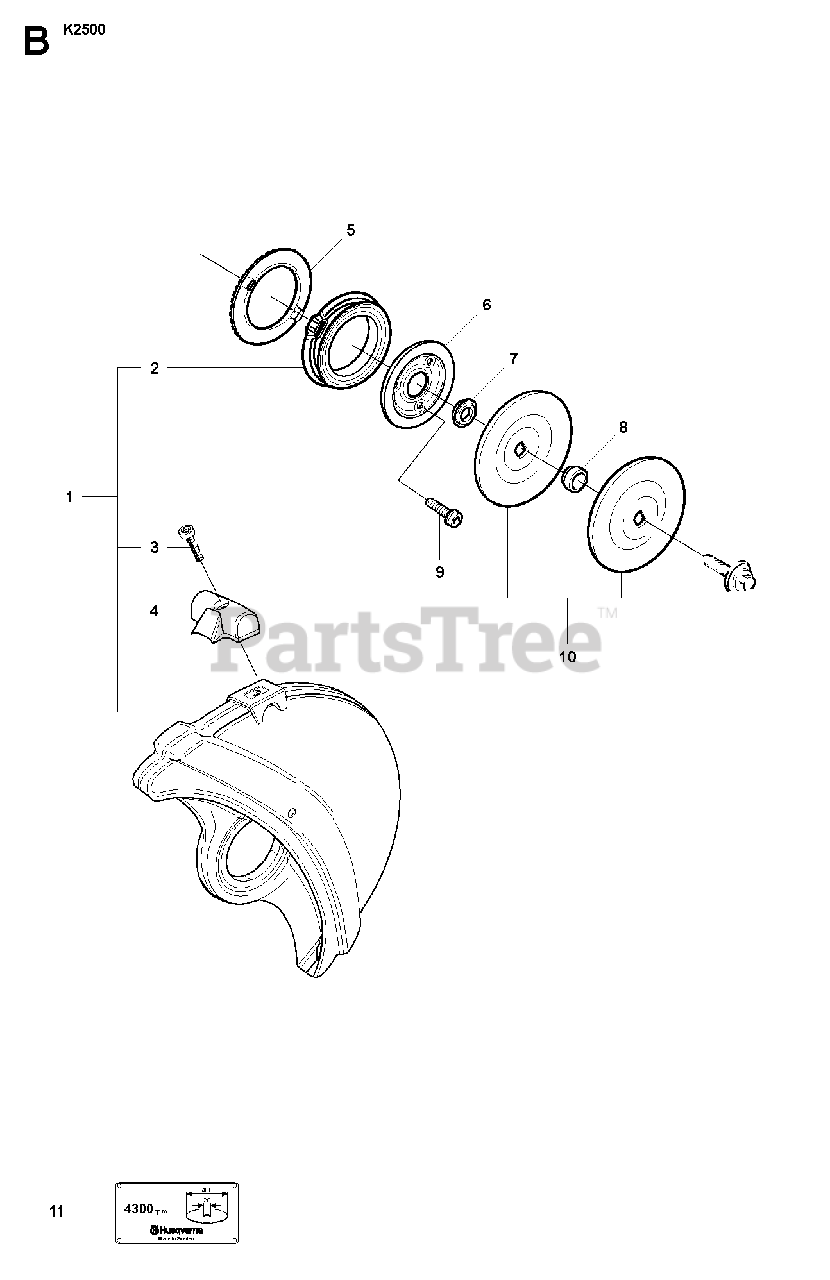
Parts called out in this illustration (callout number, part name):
1	BLADE GUARDincl. 2-4
3	SCREW ITXSCM
7	SUPPORT FLANGE
8	KITDiam 20mm
8	KITDiam 22,2mm
8	KITDiam 25,4mm
8	BUSHINGDiam 30,5mm
10	FLANGE WASHERDiam 105mm
10	FLANGE WASHERDiam 119mm
11	LABELDiam 20mm
11	LABELDiam 25,4mm
